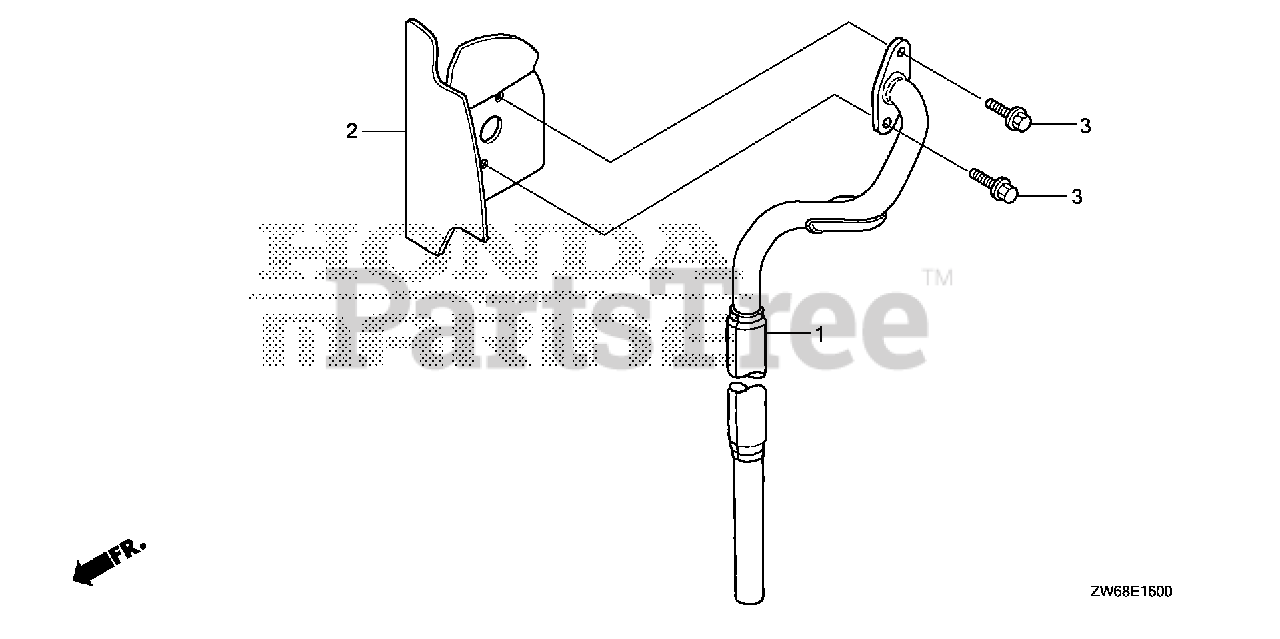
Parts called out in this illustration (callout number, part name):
1	PIPE, EX.
2	GUIDE, AIR EX.
3	BOLT, FLANGE (5X16)
